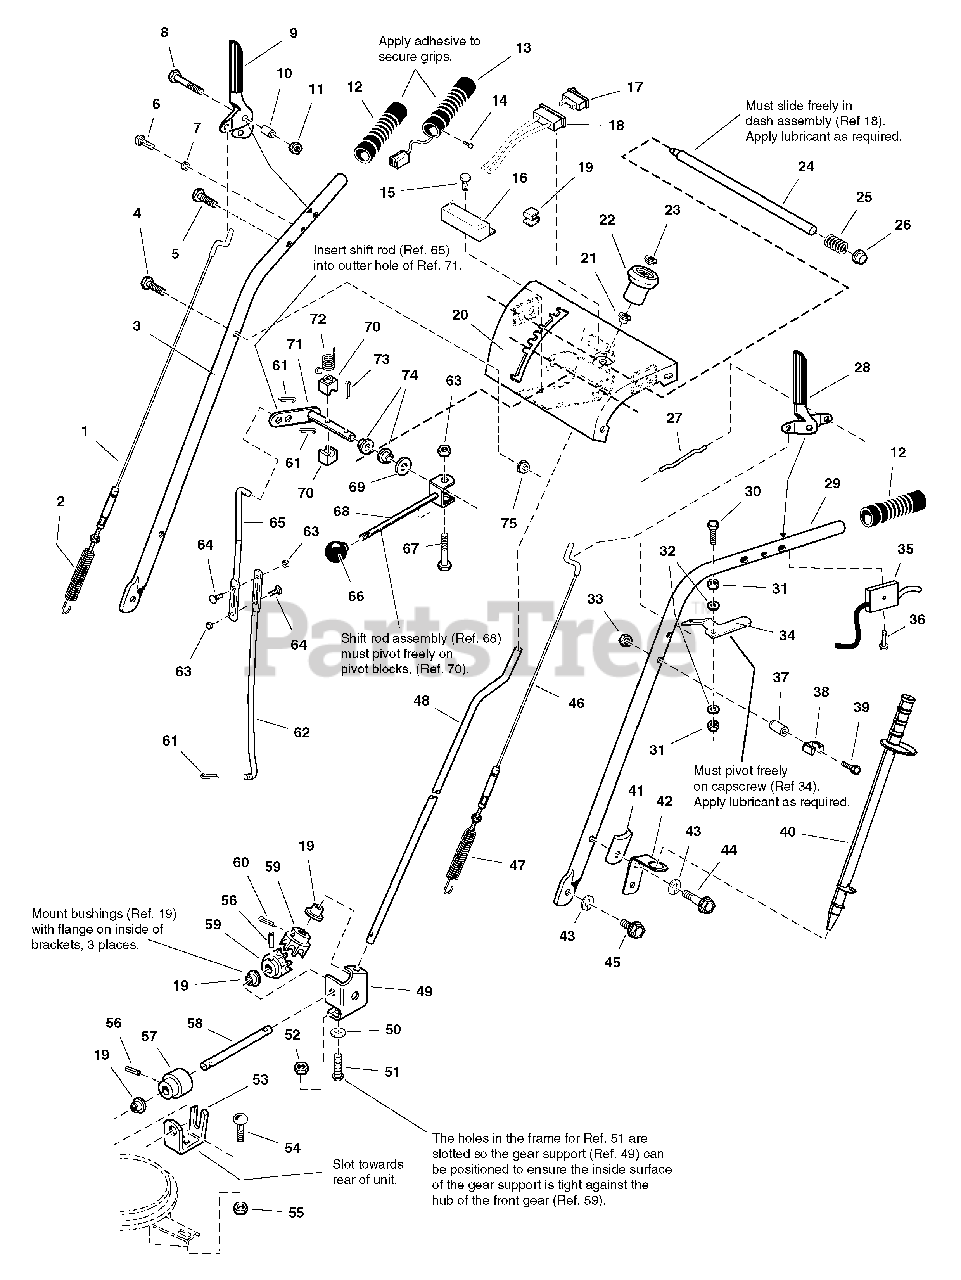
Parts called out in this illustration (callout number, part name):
1	CABLE AND SPRING ASSEMBLY, R.H. Auger
2	SPRING, Torsion
3	HANDLE, Tube, R.H.
4	CAPSCREW, Hex Head, 5/16-18 x 1-3/4 G5
5	CAPSCREW, Hex Head, 5/16-18 x 1-1/2 G5
6	SCREW, Pan Head Torx, 1/4-20 x 3/4, Thread Cutting
7	SPACER, 1/4ID x 25/64OD x 11/64LG
8	CAPSCREW, Hex Head, 1/4-20 x 1-1/2 G5
9	HANDLE, Clutch R.H.
10	SPACER
11	NUT, Hex Centerlock, 1/4-20
12	GRIP
13	HAND GRIP, Heated 1" Diameter
14	RIVET, Pop
15	CAPSCREW, Hex Head 1/4-20 x 3/4 G5
16	RESISTOR BLOCK, 2 Male Terminal
17	SWITCH, Hand Warmer
18	HARNESS, Wiring
19	CLIP, Wire
20	DASH AND SUPPORT ASSEMBLY, Tubular
21	BUSHING, 47/125ID x 437/1000OD x 1/5LG
22	KNOB, Spinner
23	NUT, Push Pal, 3/8" Diameter Stud Capped
24	ROD AND SPRING ASSEMBLY, w/Pin
25	SPRING, Complete
26	PUSH NUT, Stud Cap, 1/2
27	ROD, 4/25" Diameter, E-Coat
28	HANDLE, Clutch L.H.
29	HANDLE, Tube, L.H.
30	CAPSCREW, Hex Head, 1/4-20 x 2 G5
31	NUT, Hex Lock ESNA Light, 1/4-20NC-3B
32	WASHER, 1/4
33	NUT, Hex Lock, 10-24
34	LEVER, Pivot
35	CABLE AND HANDLE ASSEMBLY, Clutch
36	SCREW, Pan Head Torx, #10 x 1/2 Thread Cut
37	SPACER, 1-1/4 LG Beveled End
38	CLIP, Snow Stick
39	SCREW, Hex Flange Slot, #10-24 x 2-1/2
40	STICK, Snow Removal
41	CLAMP, Saddle Snow Handle E-Coat
42	BRACKET, Clean Out Tool
43	LOCKWASHER, Spring, 5/16
44	CAPSCREW, Hex Head 5/16-18 x 2 G5
45	SCREW, Hex Whiz Lock Flange, 5/16-18 x 3/4
46	CABLE AND SPRING ASSEMBLY, L.H. Traction
47	SPRING, Extension
48	ROD, 3/8" Diameter, 26"LG, E-Coat
49	SUPPORT, Gear, Black
50	NUT, Push for 1/4 Diameter Thread
51	CARRIAGE BOLT, 1/4-20 x 5/8 G5
52	NUT, Hex Flange, 1/4-20, Whiz Lock Small
53	SUPPORT, Worm
54	CARRIAGE BOLT, 5/16-18 x 3/4 G5
55	NUT, Hex Keps Conical Washer, 5/16-18
56	PIN, Spring 1/8 x 3/4
57	WORM, Chute, L.H.
58	ROD, 3/8" Diameter, Chute Worm E-Coat
59	GEAR, Powdered Metal, Metafusion
60	PIN, Cotter 1/4 x 1
61	PIN, Quick
62	ROD, 3/4" Diameter
63	NUT, Hex KEPS, 1/4-20, Conical Washer
64	CARRIAGE BOLT, 1/4-20 x 3/4 G5
65	ROD, 3/4" Diameter, Shift Upper E-Coat, 11-19/50LG
66	KNOB, Intermediate Thread, 3/8-16
67	SCREW, Hex Whiz Lock Flange, 1/4-20 x 2-1/4
68	ROD AND CLEVIS ASSEMBLY, Shift, Threaded
69	WASHER, 1/2
70	BLOCK, Pivot, 3/4 x 3/4, Powdered Metal
71	ROD AND ARM ASSEMBLY, Pivot
72	SPRING, Torsion
73	CLIP, Hair Pin
74	BUSHING, 1/2ID x 3/4OD x 1/4LG
75	NUT, Hex Flange, 5/16-18 ESNA
